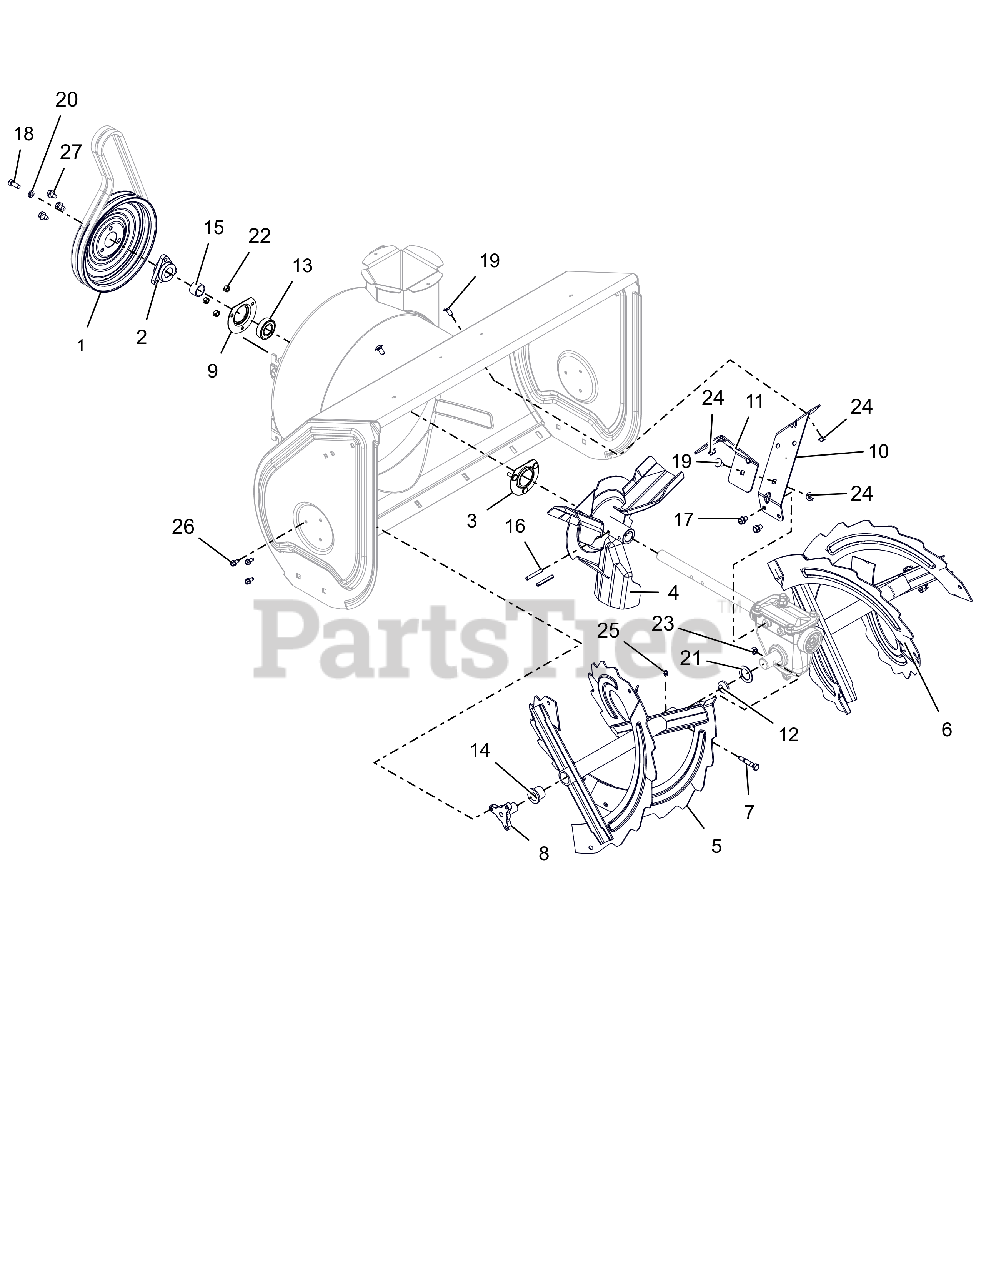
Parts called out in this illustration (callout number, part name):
1	PULLEY, SPIN FORM DUAL GROOVE
2	PULLEY HUB, D-BORE .87 DELUXE
3	BEARING FLANGE
4	IMPELLER, 3 BLADE-14"
5	RAKE, RH W/ZERK - 30"
6	RAKE, LH W/ZERK - 30"
7	BOLT, SHEAR - DELUXE
8	SUPPORT, RAKE BUSHING
9	BEARING FLANGE
10	BRACKET, GEARCASE SUPPORT - LH
11	BRACKET, GEARCASE SUPPORT - RH
12	PLUG, RAKE TUBE
13	BRG-BALL .876 X 1.750 X .50
14	BSHG-FLG, NY.778 ID X 1.018 OD
15	BSHG,SPCR .895X1.065X.693
16	PIN-ROLL .250X1.75
17	BOLT, SEMS .31-18X.50 GR5 YWZC
18	BLT-HEX .31-24X.75 YWZC GR5
19	BLT-RDHDSQSHNK.31-18X.62 YZ-LK
20	WSHR-LK .312X.097 HVY YWZC
21	WSHR-FL-STL 1.010X1.505X.062YZ
22	@NUT-LK-CTR .25-20 YWZC
23	@NUT-LK-CTR .31-18 YWZC
24	@NUT-LK-TOP-FLG .31-18 YWZC
25	ZERK,FITTING .25X.125 DRIVE IN
26	SCR-TAP .25-20X.50 HWH TR YWZ
27	@SCR-TAP .31-18X.50 HWH TR YWZ
